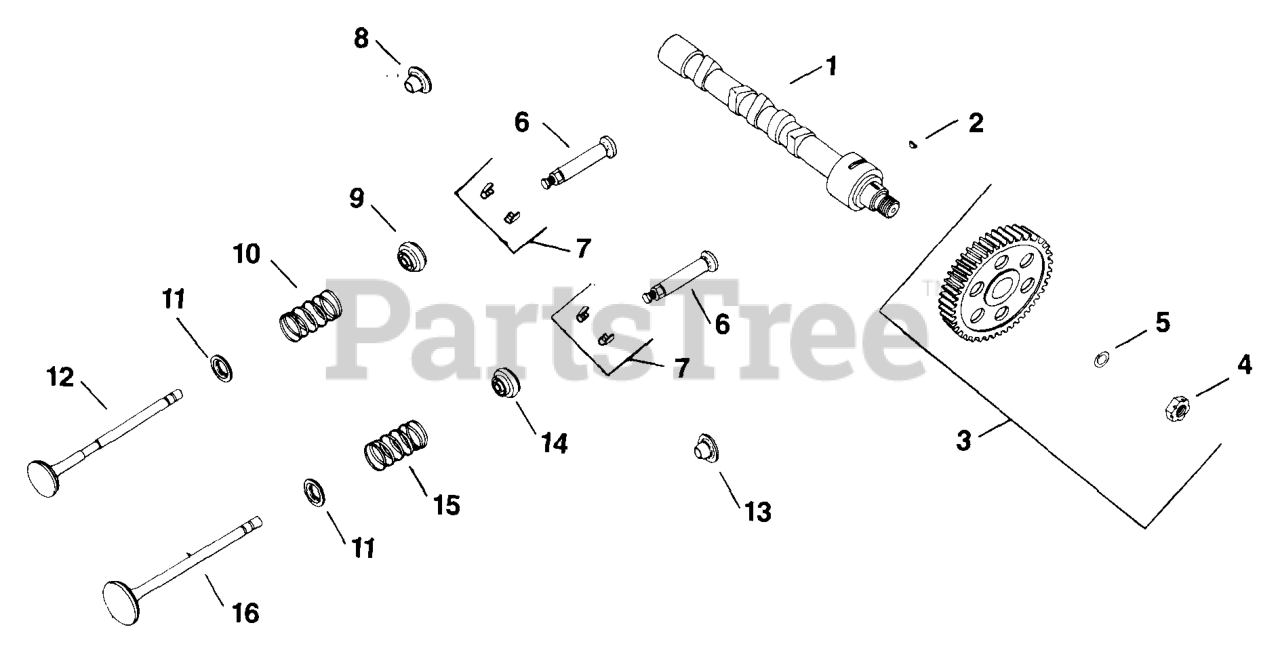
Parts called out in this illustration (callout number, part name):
2	KEY, 1/8" X 1/2"
3	KIT, CAMSHAFT GEAR - (#DSC)
4	NUT - DISCONTINUED
6	TAPPET - DISCONTINUED
7	KIT, RETAINER
10	SPRING, INTAKE VALVE - DISCONTINUED
11	RETAINER, SPRING
15	SPRING, INTAKE VALVE - DISCONTINUED
